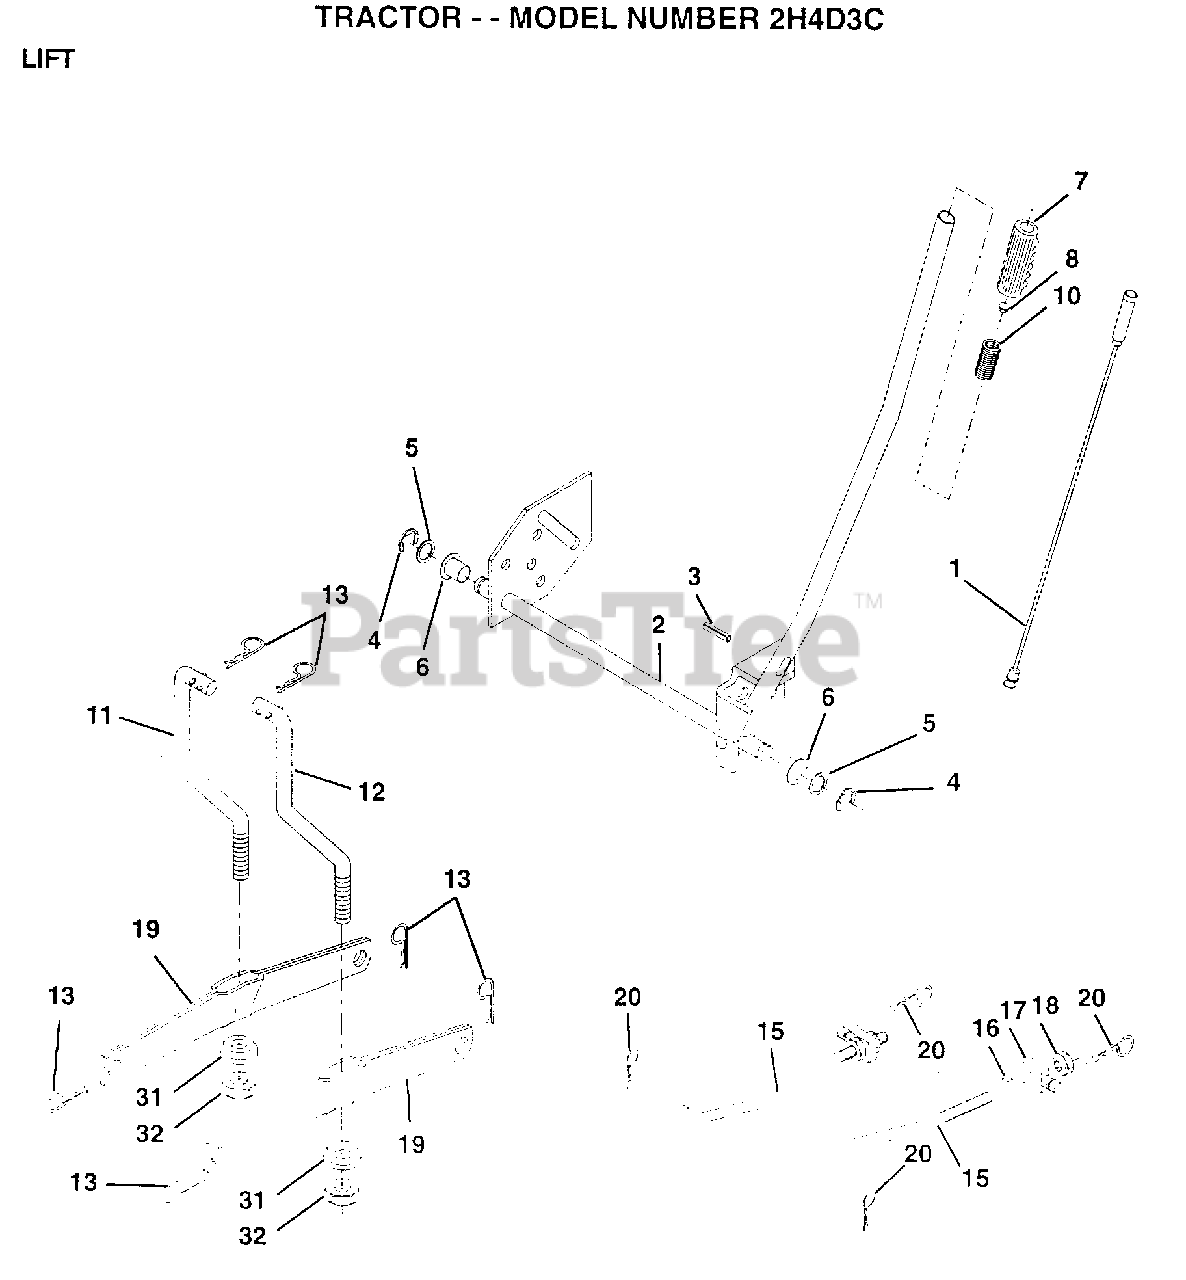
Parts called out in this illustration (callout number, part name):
1	WIRE.ASM.INNER
2	SHAFT.ASM.LIFT.RH
3	PIN GROOVE
5	WASHER
6	NYLON BEARING
7	GRIP
15	LINK.FRONT
16	NUT
17	TRUNION
18	NUT.LK.W/WSH.1/2.
19	ARM SUSP REAR
20	RETAINER.SPRING
31	BEARING PVT LH
32	NUT.CROWNLOCK.3/8
